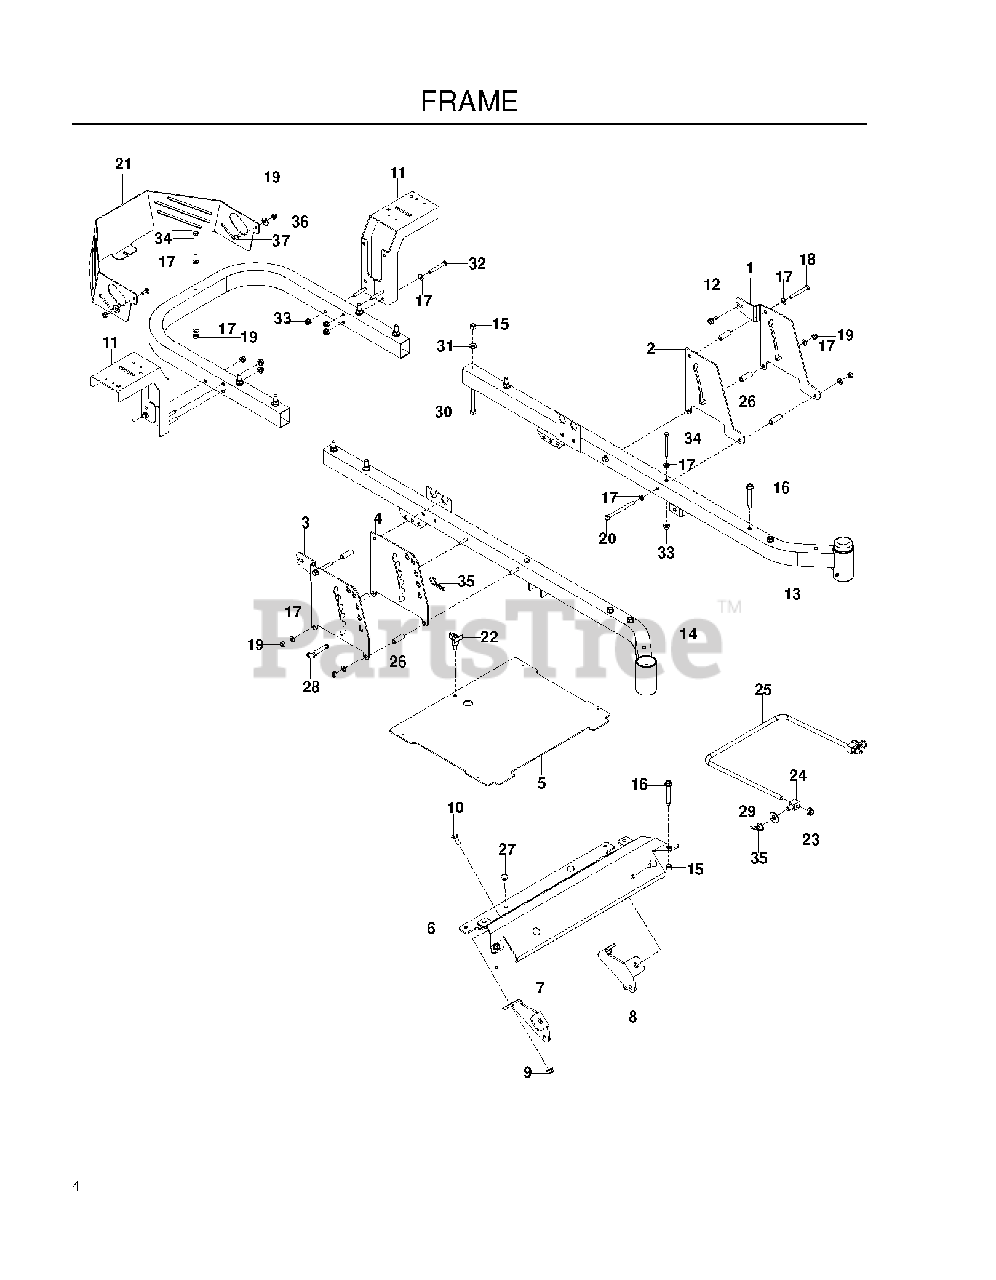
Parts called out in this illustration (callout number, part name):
1	PLATE, OUTER BRAKE, BLACK
2	PLATE, BRAKE LATCH, BLACK
4	PLATE, DECK HEIGHT, BLACK
5	PLATE, FOOT W/DECALS SPZ
6	FOOT REST, MED BLUE
7	MOUNT, STRUT, RT, BLK
8	MOUNT, STRUT, LT, BLK
9	NUT 3/8-16 HEX FLG NYLOC ZD
10	RHSNB 3/8C X 1
11	SUPPORT, FENDER, BLACK
12	BOLT 5/16-18 X 3/4
13	FRAME, RT, BLUE
14	FRAME, LT, BLUE
15	NUT 3/8-16 NYLOC
16	ENGINE BOLT, SPECIAL
17	FLAT WASHER 5/16 SAE
18	BOLT 5/16C X 2 1/2
19	NUT 5/16 NYLOC
20	HCS 5/16C X 4
21	GUARD, REAR BLUE
22	KNOB W/STUD
23	7/16-14 HEX NUT W/NYL RING ZD
25	LINK, FRONT SUSP.
26	SPACER, .334 ID X .5 OD X 1.5
27	GROMMET, BUMPER
28	HITCH PIN
29	WASH USS FLAT 1/2
30	HCS 3/8C X 3
31	WASHER 3/8 SAE FLAT
32	CAPSCREW
33	5/16-18 NYLOC FLANGE NUT
34	HCS 5/16C X 2-3/4
35	HAIRPIN #4
36	WASHER 1/4 FLAT
37	BOLT 5/16C X 3/4" CARRIAGE
